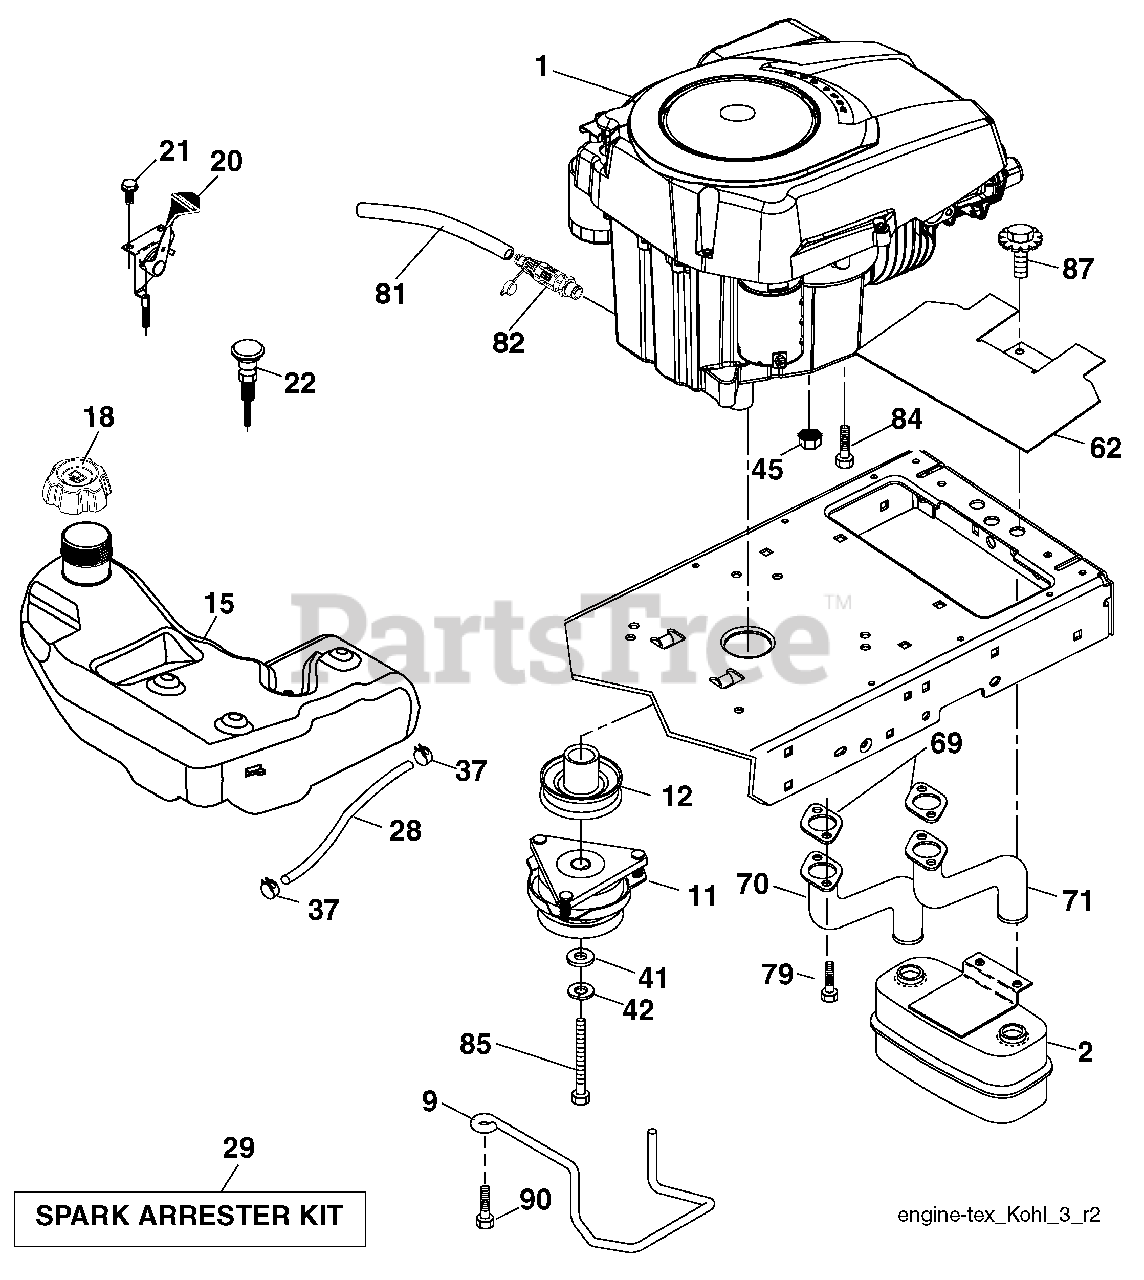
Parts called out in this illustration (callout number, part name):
9	Keeper Belt Engine
11	Clutch Electric
12	Pulley Engine
15	Tank Fuel 4.0
18	Cap Asm
20	Control Throttle
21	Screw #10 x 0.750
22	Control Choke
28	Fuel Line
29	Spark Arrester Kit
37	Clamp Hose
41	Washer 1-1/2 OD x 15/32 ID x .250
42	Washer Lock 7/16
45	Nut Keps Hex 1/4-20 unc
62	Shield Heat Muffler
70	Tube Exhaust LH
71	Tube Exhaust RH
79	Screw Socket HD 5/16-18 x .75
81	Tube Drain Oil Easy
82	Valve Oil Drain
84	Screw 3/8-16 x 1
85	Bolt Hex 7/16-20 x 4.00 Gr. 5
87	Bolt 5/16-18 unc x 3/4 w/Sems
90	Screw 3/8-16 x 1
